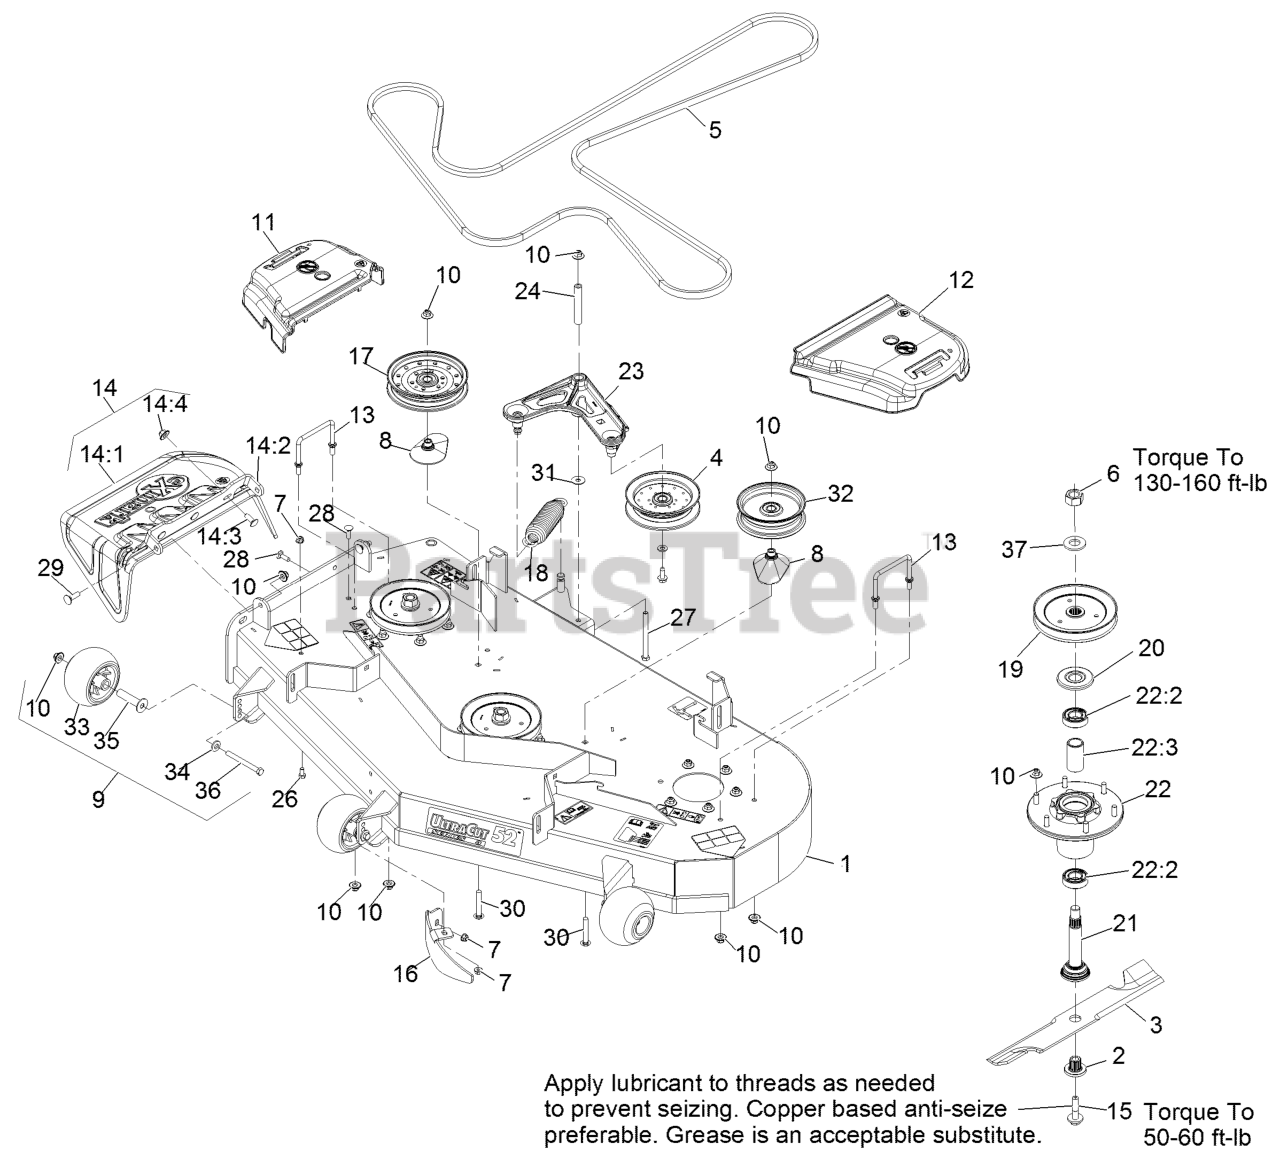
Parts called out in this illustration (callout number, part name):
1	ASM-DECK W/DECALS, 52
2	BUSHING,SPLINED
5	BELT-B162.50
6	NUT-HEX
7	NUT-HF, NI
8	SPACER-PULLEY
9	KIT, ANTI-SCALP ROLLER
10	Nut-Nyloc 3/8-16 Flg
11	COVER-BELT, RH
12	COVER-BELT, LH
13	WIREFORM-COVER
14	ASM,DISCHARGE CHUTE
14:1	CHUTE,DISCHARGE
14:2	BRACKET,DISCHARGE CHUTE
14:3	SCREW-CARR
14:4	Nut-Nyloc 3/8-16 Flg
15	SCREW,SEMS 1/2-20 X 2.19
16	BAFFLE-DOGLEG, LZE-PNS-52
18	SPRING-EXTENSION
19	SHEAVE,BLADE DRIVE 6.50
20	GUARD,BEARING TOP .989
21	ASM-SPINDLE AND SEAL
22	ASM-CUTTER HSG WITH BEARINGS
22:2	BEARING-BALL
22:3	SPACER-BEARING
23	IDLER ARM ASM
24	BUSHING
26	SCREW-HH
27	SCREW-HH
28	BOLT-CARR
29	BOLT-CARR
30	SCREW-CARR
32	IDLER-PULLEY, FLAT
33	ROLLER-SCALP, ANTI
34	WASHER-BELLEVILLE
35	AXLE, ROLLER
36	SCREW-HH 3/8-16 X 3 3/4 GR 8
